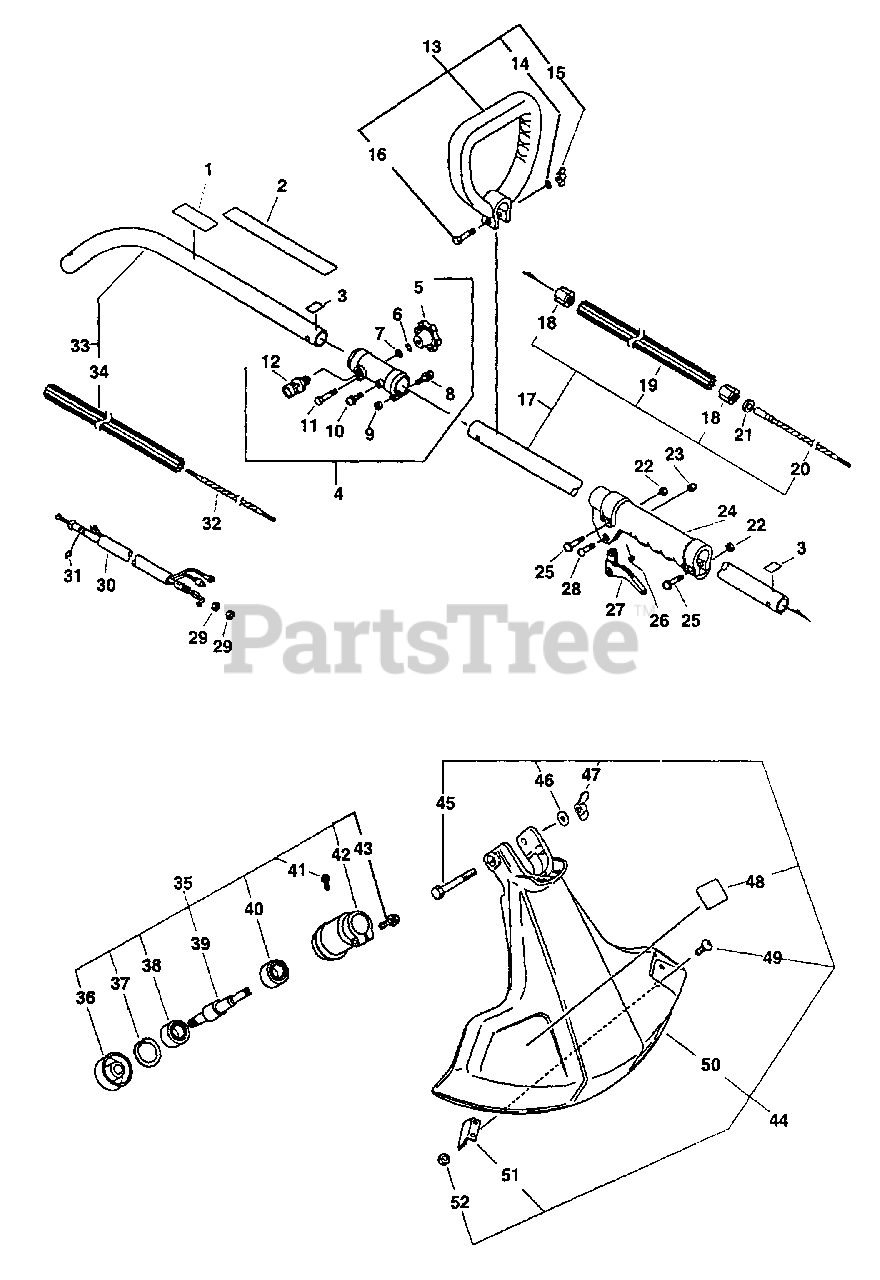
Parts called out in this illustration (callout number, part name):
1	LABEL, CAUTION
2	LABEL, CAUTION
3	LABEL - ALIGNMENT
4	HOLDER, MAIN PIPE
5	KNOB, FASTENER
6	WASHER, SPRING 5
7	WASHER, FLAT 5.5×10×0.8
8	BOLT 5×30
9	NUT M5
10	SCREW 5×12
11	BOLT 5×35 SP
12	LATCH ASSY
13	HANDLE ASSY
14	WASHER, 1/4"
15	NUT, WING 1/4"-20
16	BOLT 1/4"-20×1-1/2"
17	MAIN PIPE ASSY
19	LINER - FLEXIBLE
20	DRIVESHAFT - FLEXIBLE
21	STOPPER
22	NUT M5
23	NUT, LOCK M5
25	SCREW - 5×25
26	SPRING, THROTTLE
27	TRIGGER, THROTTLE
30	CABLE, THROTTLE
31	E-RING 4
32	DRIVESHAFT - FLEXIBLE
33	MAIN PIPE ASSY
34	LINER - FLEXIBLE
35	GEAR CASE ASSY
36	PLATE, ADAPTER - UPPER
37	E-RING 30
38	BEARING, BALL 6200
39	GEAR, SHAFT
40	BEARING, BALL 6200
41	SCREW 4×10
42	CASE, GEAR
43	BOLT - 5×25
44	SHIELD ASSY
45	BOLT 1/4"-20×2"
46	WASHER, 1/4"
47	NUT, WING 1/4"-20
48	LABEL, CAUTION
49	SCREW 5×16
50	SHIELD, DEBRIS
51	CUTTER, LINE
52	NUT M5
